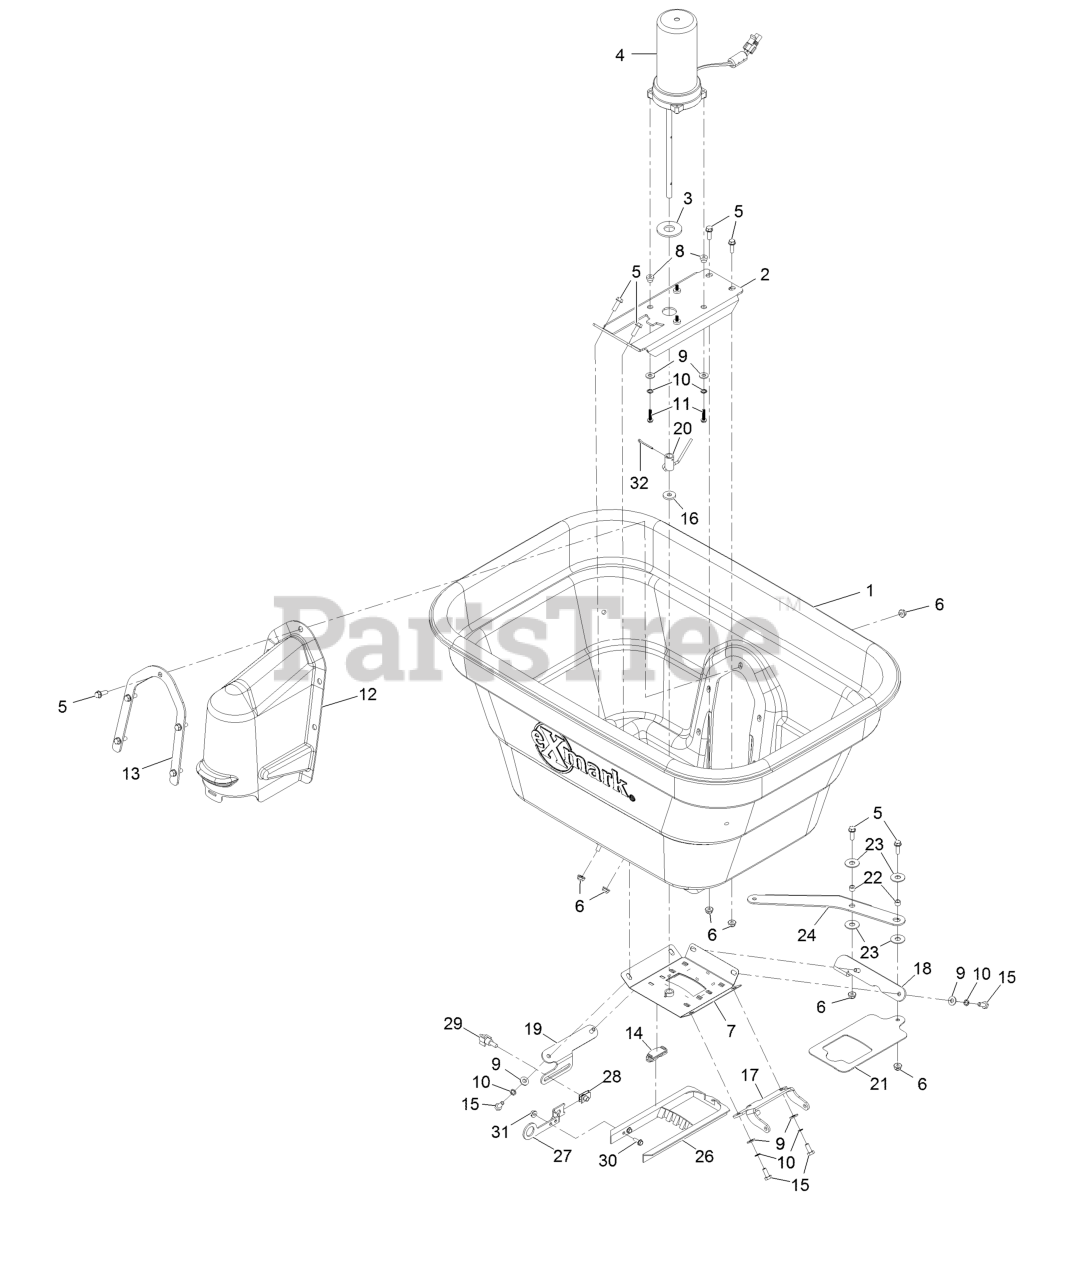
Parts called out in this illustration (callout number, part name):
1	Hopper-Spreader, 175 Lb (Exmark)
2	Mount-Motor
4	Motor-Spreader
5	Screw-Machine 1/4-20 X 3/4
6	Nut-Nyloc 1/4-20 Flg
7	Gate-Bearing
8	Spacer-Flanged
9	Washer-1/4 SAE
10	Washer-Lock, Int
11	Screw-SHWH 10-32 X 7/8
12	Cover-Motor
13	Support-Cover
14	Guide-Rate, Gate
15	Screw-HH 1/4-20 X 5/8
16	Washer-Felt
17	Mount-Deflector
18	Mount-Gate, Pivot
19	Mount-Gate, Pivot
20	Weld-Agitator
21	Gate-Spreader, Seed
24	Arm-Engagement
26	Diffuser
27	Bracket-Accuway, Slide
28	Nut-Retainer-Panel 1/4-20
29	Knob-Star, Three
31	Nut-Flange #10-24 Top Lock
32	Pin-Cotter
